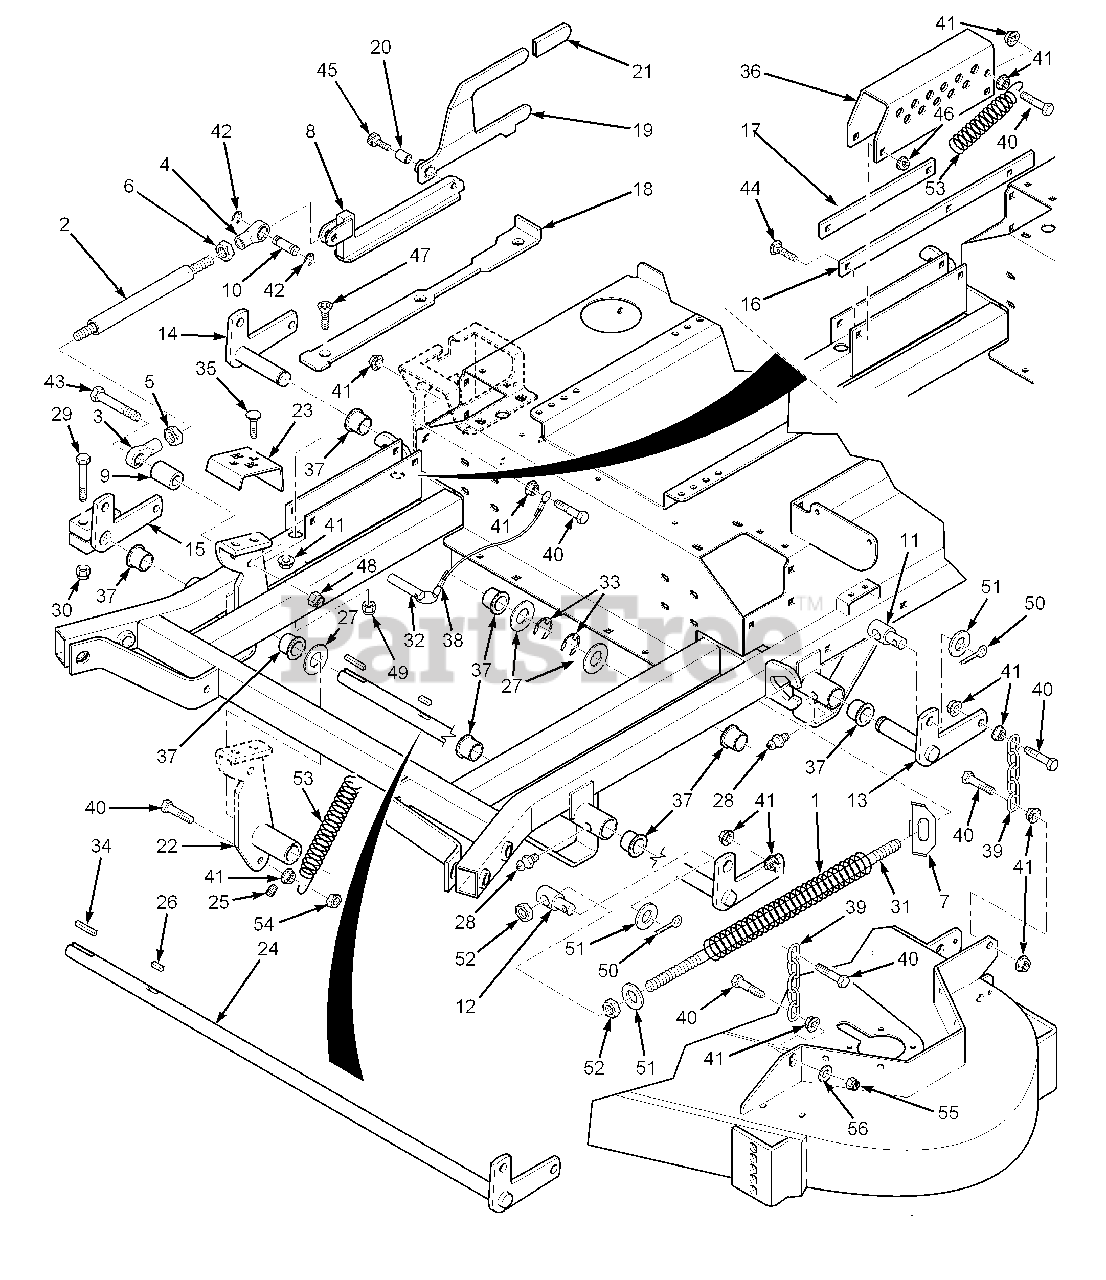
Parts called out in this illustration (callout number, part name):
1	Spring, Deck Lift
2	Link, Deck Lift
3	Rod End, Female - 1/2-20 RH
4	Rod End, Female - 1/2-20 LH
5	Nut, Jam 1/2-20 RH
6	Nut, Jam 1/2-20 LH
7	Flatwasher, Spring Stop
8	Slide Weldment, Height Adjustment
9	Spacer, Decklift Pedal
10	Pin, Decklift
11	Swivel Joint, LH
12	Swivel Joint, RH
13	Bellcrank Weldment, LH Rear
14	Bellcrank Weldment, RH Rear
15	Bellcrank Weldment, RH Front
16	Guide, Short
17	Guide, Long
18	Lockplate, Decklift
19	Deck Latch
20	Bushing, .502 ID.
21	Grip, Deck Latch
22	Footplate Weldment, Decklift
23	Footplate, Height Adjustment
24	Bellcrank Weldment, LH Front
25	Set Screw, 5/16-18 x 1/2" Sq. Head
26	Key, 1/4 x 1/4 x 3-1/4"
27	Flatwasher, 1"
28	Grease Fitting
29	Bolt, Hex Head 7/16-14 x 2-1/2"
30	Nut, Hex Elastic Stop 7/16-14
31	Stud, 5/8-11 x 22.0"
32	Ring Pin, 1/2 x 3.30"
33	Ring, Retaining 1" External "E"
34	Key, 1/4 x 1/4 x 1-1/4"
35	Bolt, Carriage 3/8-16 x 1-1/4"
36	Bracket, Cutting Height Adjustment
37	Bushing, 1.003 ID.
38	Lanyard, Deck Height Pin
39	Chain
40	Bolt, Hex Head 3/8-16 x 1-1/2"
41	Nut, Hex Serrated Flange 3/8-16
42	Ring, Retaining 1/2" External "E"
43	Bolt, Hex Head 1/2-13 x 3"
44	Bolt, Carriage 5/16-18 x 1"
45	Bolt, Shoulder 1/2 x 3/4"
46	Nut, Hex Serrated Flange 5/16-18
47	Screw, Cap 5/16-18 x 3" FHHS
48	Nut, Hex Elastic Stop 1/2-13
49	Nut, Hex Elastic Stop 5/16-18
50	Cotter Pin, 3/16 x 1"
51	Flatwasher, 5/8"
52	Nut, Hex 5/8-11
53	Spring, Helper
54	Locknut, 3/8-16 Center Lock
55	Nut, 3/8-16 Elastic Stop
56	Flatwasher, 3/8"
